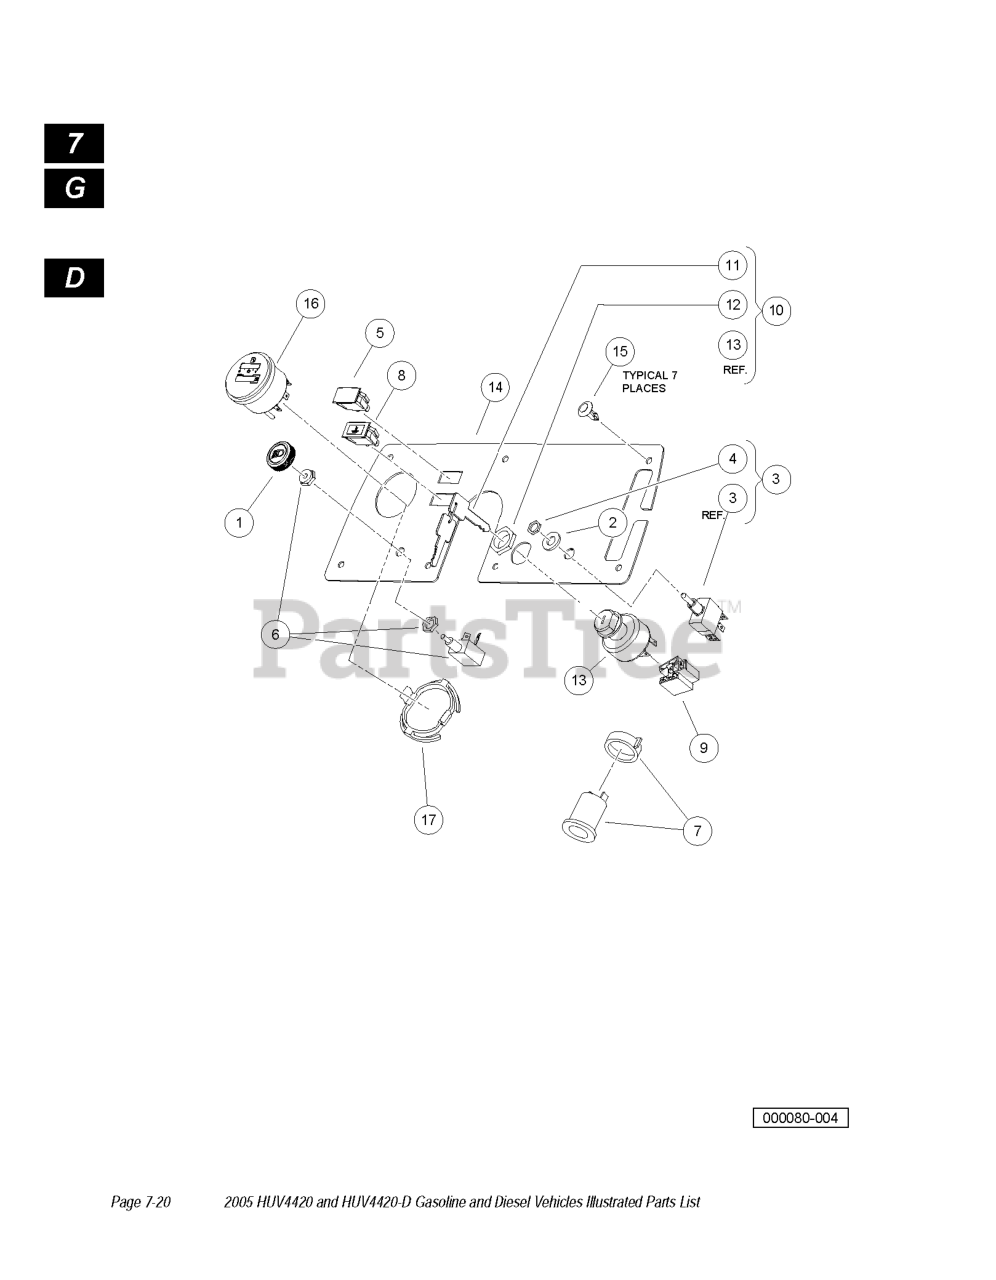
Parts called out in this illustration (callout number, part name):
1	LIGHT SWITCH KNOB
2	WASHER, 7/16 FLAT
3	TOGGLE SWITCH
5	LIGHT, OIL
6	SWITCH, LIGHT
7	ACCESSORY RECEPTACLE
8	2IGHT, INDICATOR, COLLANT TEMP
10	KEYSWITCH, DIESEL
11	KEY SET, AWD DIESEL
14	PANEL, INSTRUMENT, DIESEL
15	SCREW, TUFLOK PANEL, 1/4
16	GAUGE FUEL-HOUR SEP GND
17	CLIP METER ROUND
